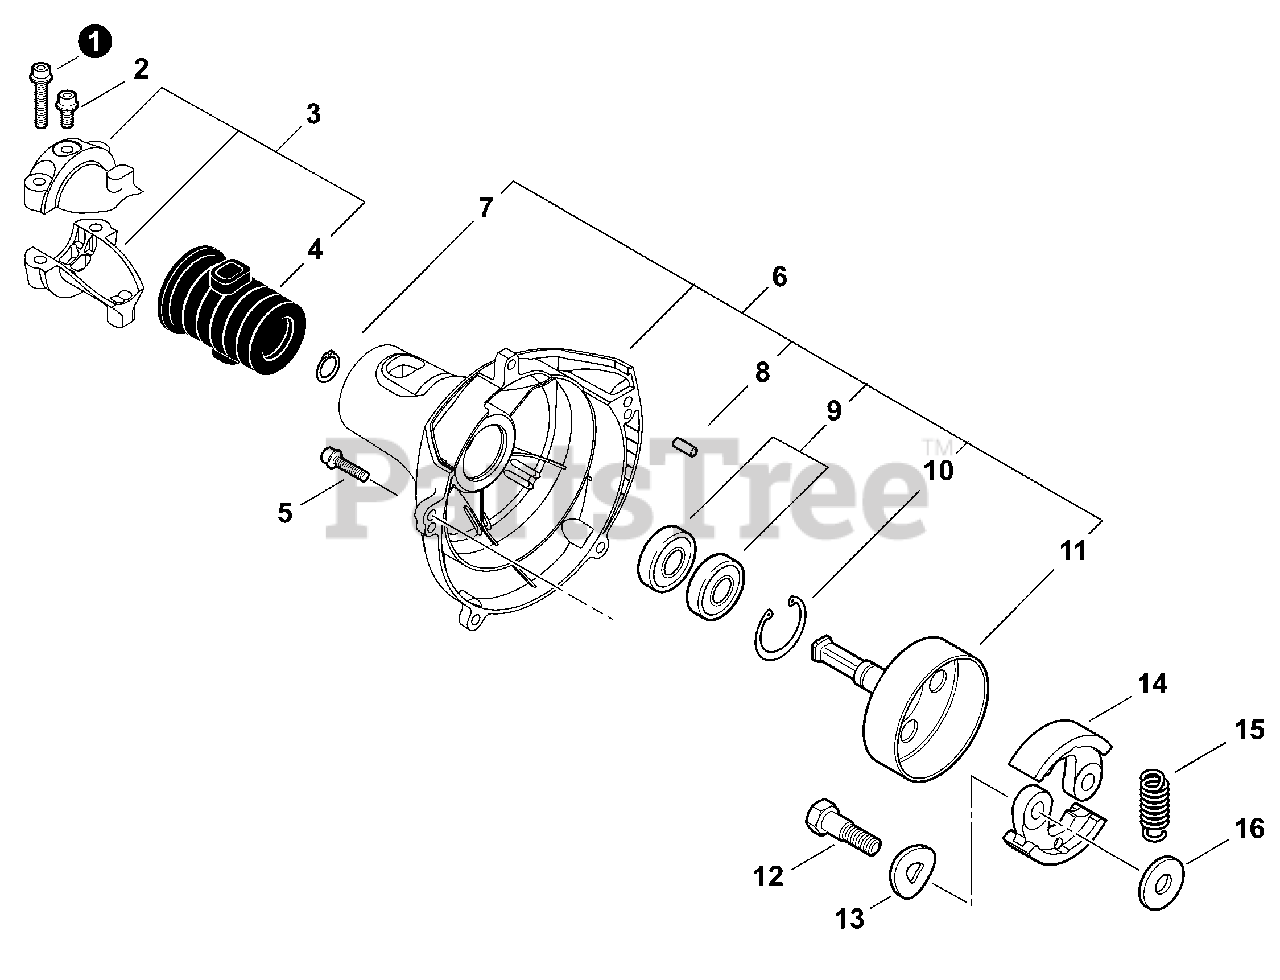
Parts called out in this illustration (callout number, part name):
1	BOLT 5×25
2	SCREW 5×10
3	FIXTURE KIT, MAIN PIPE
4	CUSHION
5	BOLT 5×20
6	CASE ASSY, FAN
7	RING, RETAINING - 12
8	PIN, LOCATING 4×8
9	BEARING, BALL 6001
10	RING, SNAP 28
11	DRUM, CLUTCH
12	BOLT, CLUTCH 8×7.9×M6
13	WASHER, SPRING 8.5×16×0.5
14	SHOE, CLUTCH
15	SPRING, CLUTCH
16	WASHER 6.2×19×1.0
